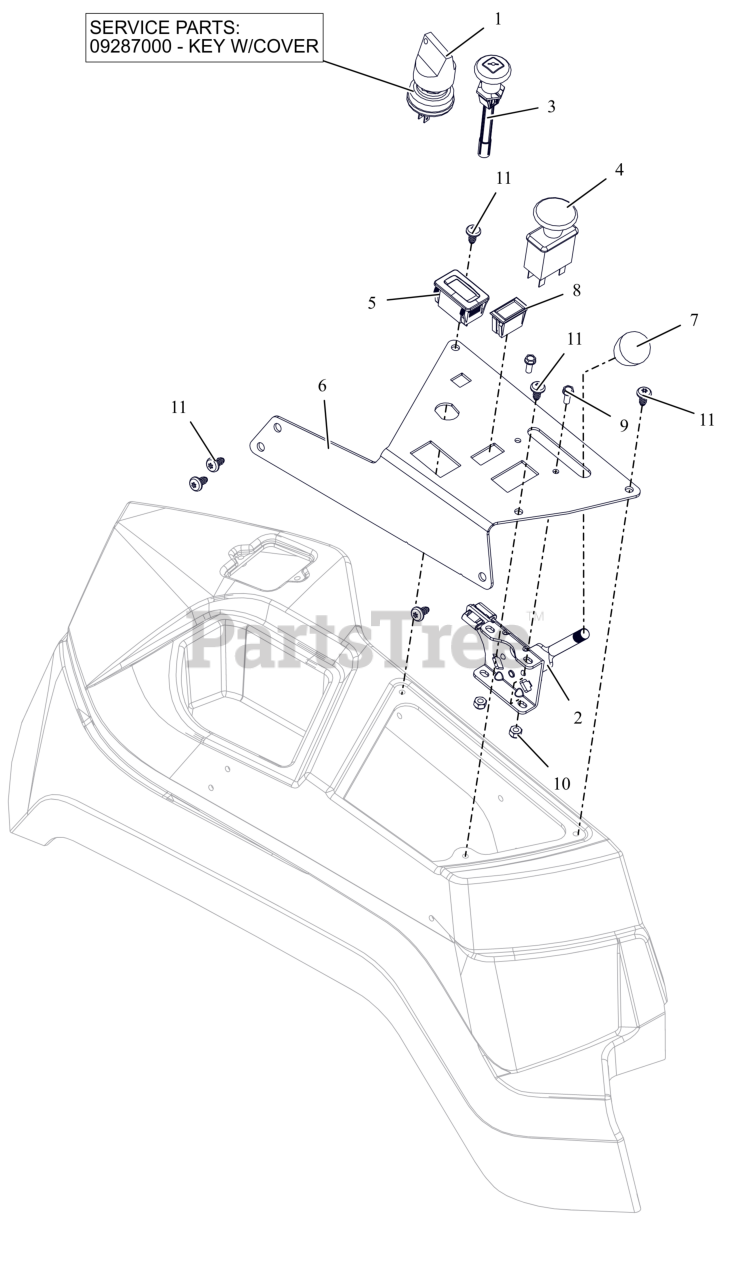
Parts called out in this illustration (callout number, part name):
1	SWITCH, IGNITION
1	KEY, W/ SHIELD
2	CABLE, PRO THROTTLE CONTROL
3	CABLE - CHOKE, SNAP-IN
4	SWITCH, CLUTCH
5	HOUR METER
6	PLATE, APEX CONTROL PANEL
7	KNOB-CONTROL-BLACK .38-16X.50
8	SWITCH,BLANK
9	BLT, HWH #10-24X.50 ZCC
10	NUT-LK-NYL #10-24 G2 ZCC
11	SCR-PAN .25-15X.50 6L H/LZB500
